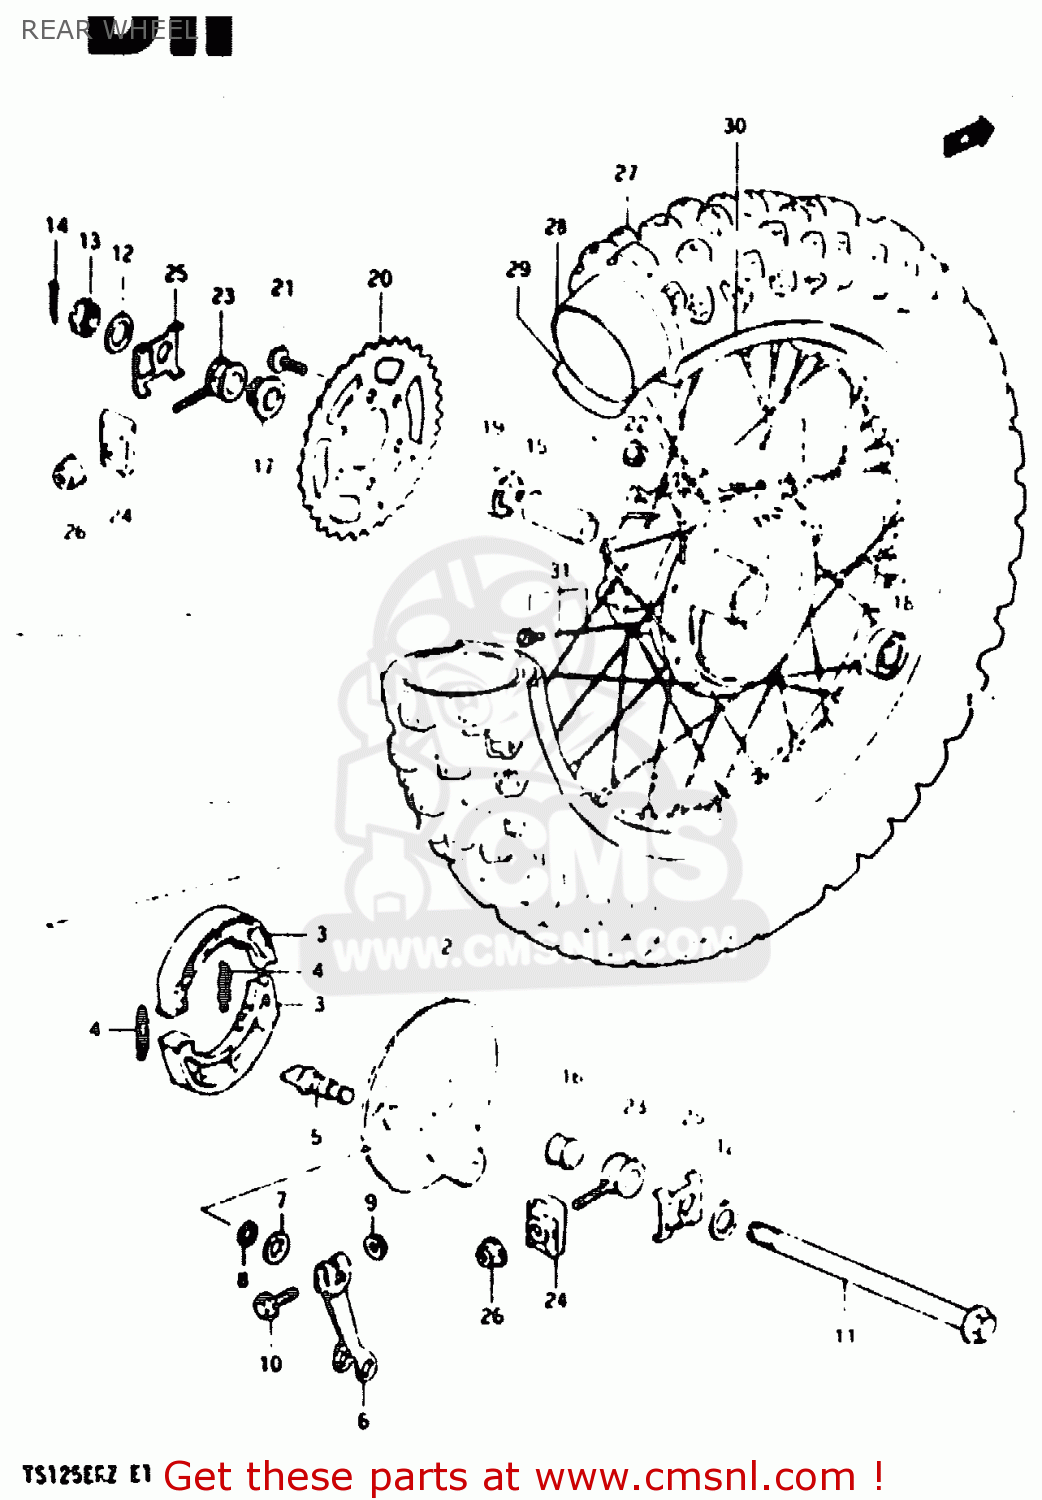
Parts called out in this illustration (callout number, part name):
1	HUB,RR WHEEL
2	PANEL,REAR HUB
3	SHOE,BRAKE (MCA)
4	SPRING(L:34)
5	CAM,FRONT BRAKE
6	LEVER,RR BRAKE CAM
7	WASHER (14.5X22X1.6)
8	O-RING (D:2.4 ID:13.8)
9	NUT
10	BOLT 6X35
11	AXLE,REAR
12	WASHER
13	NUT
14	COTTER PIN
15	SPACER(15.3X21.7X97)
16	SPACER,REAR AXLE
17	SPACER,REAR AXLE
18	BEARING
19	BEARING
20	SPROCKET,REAR
21	BOLT(8X31)
22	NUT
23	ADJUSTER,CHAIN
24	PLATE,CHAIN ADJUSTER
25	WASHER,CHAIN ADJUSTER GUIDE
26	NUT
27	TIRE
28	TUBE ASSEMBLY,WHEEL,INNER
29	PROTECTOR,INNER TUBE
30	RIM,RR WHEEL 1.85X18
31	SPOKE ASSY,RR WHEEL
